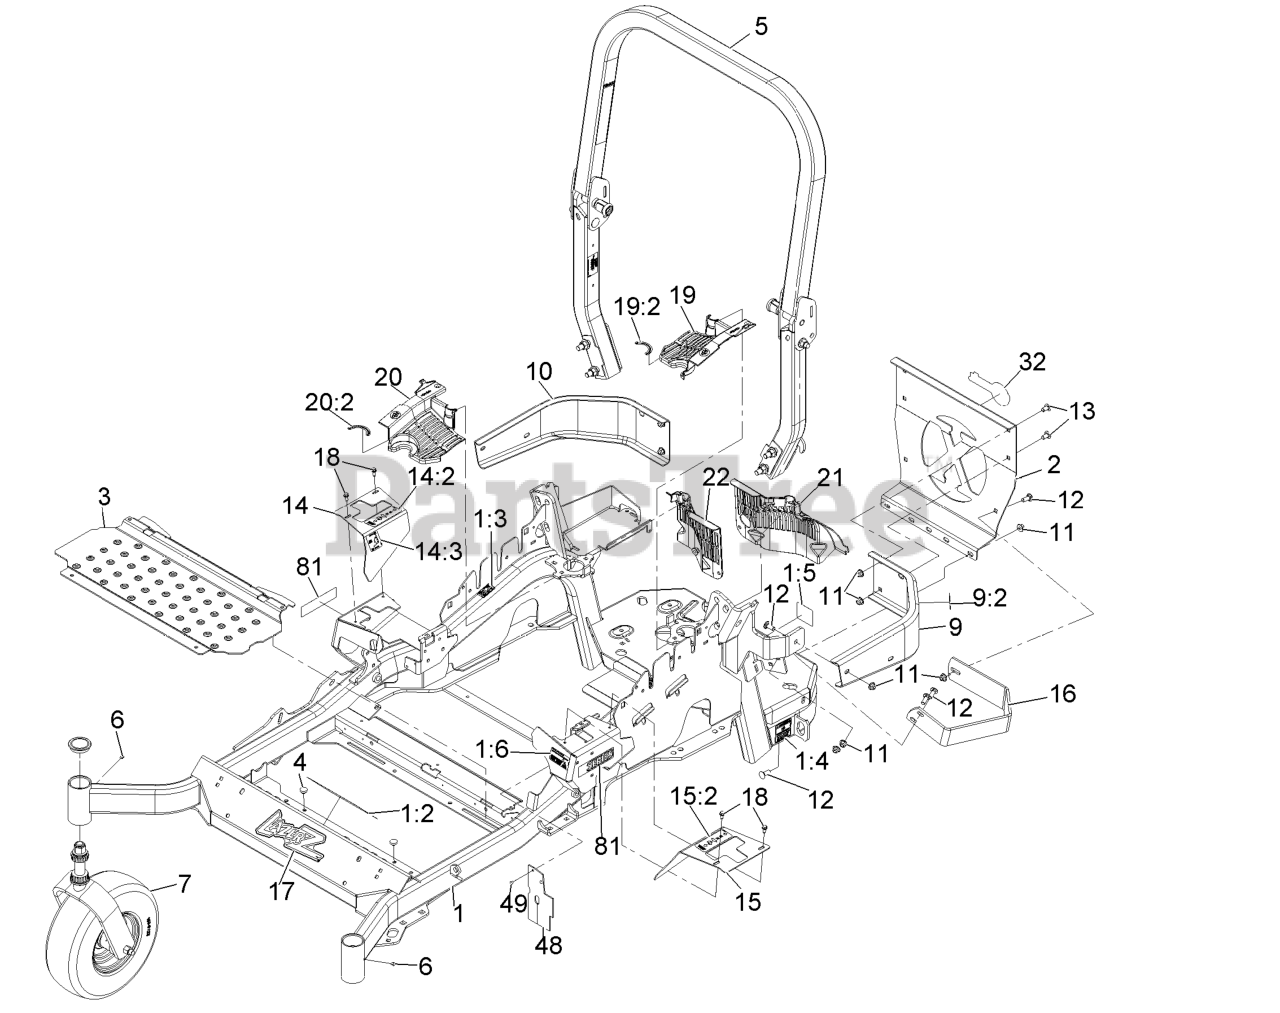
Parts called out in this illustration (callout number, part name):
1	MAIN FRAME ASM
1:2	DECAL-SLOPE
1:3	DECAL-CAUTION
1:4	DECAL-BELT DRIVE
1:5	DECAL-SPARK ARRESTER
1:6	DECAL-FUEL FILL
2	PLATE,REAR GUARD
5	ROPS ASM
7	Asm,Front Caster W/Fork
9	LH BUMPER ASM
9:2	DECAL-CAUTION
10	BUMPER-RH
11	NUT-HF, NI
12	SCREW-CARR
13	SCREW-CARR
